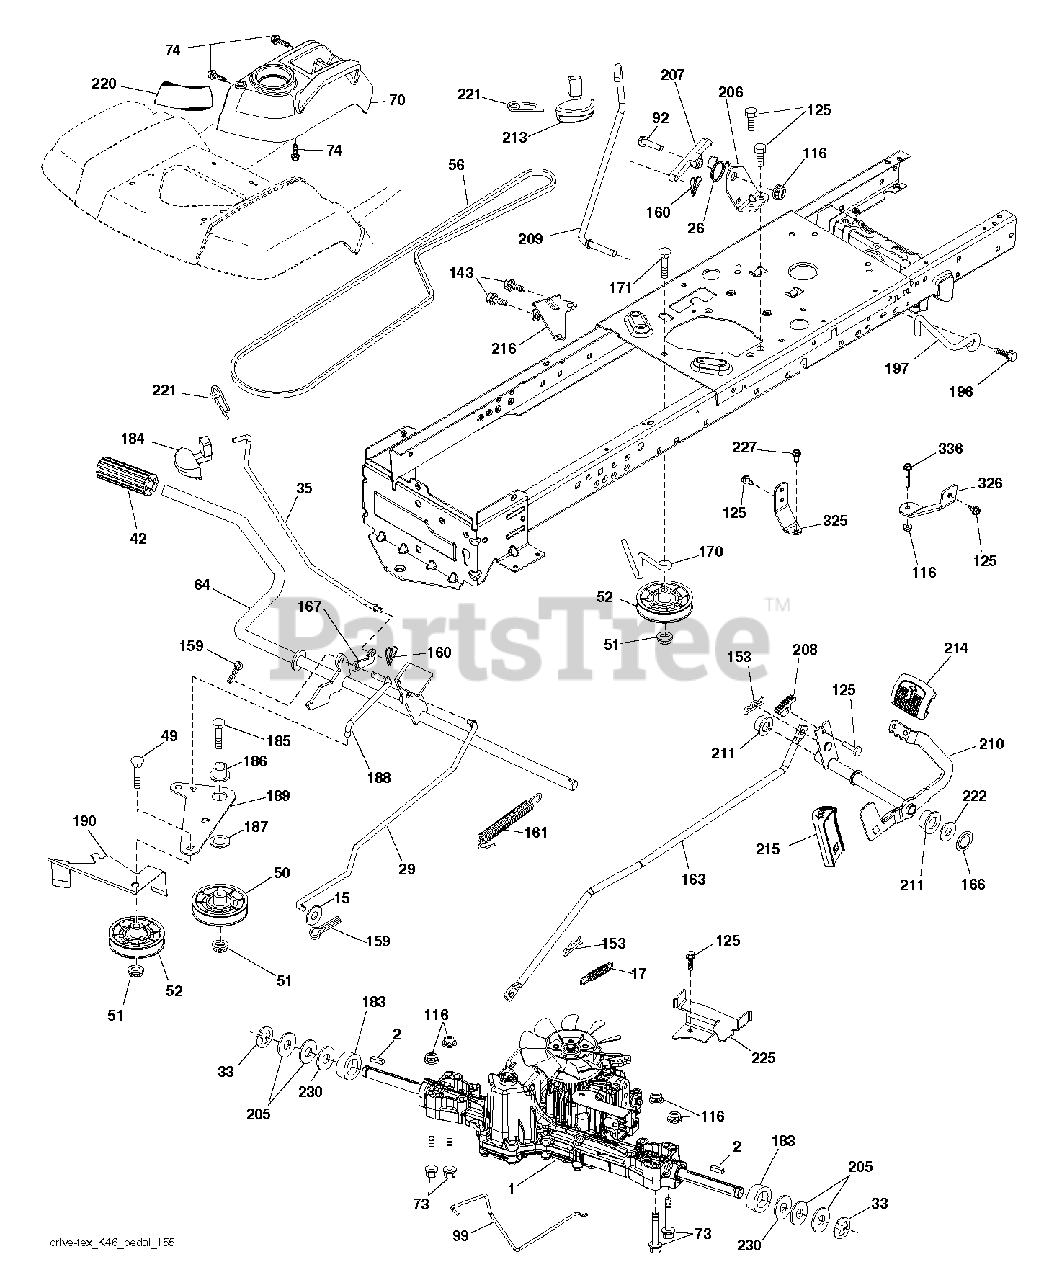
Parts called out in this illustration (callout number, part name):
2	SQUARE KEY
15	WASHER
17	SPRING.BRAKE.K46.GREEN
26	SPRING.RETURN.CRUISE
29	ROD.BRAKE.K46
33	E RING HYT
35	ROD .BRAKE. PARKING. GT. HUSQ.
42	PEDAL COVER T
50	IDLER.FLAT.910.OFFSET
51	NUT LOCK FLG 3/8-16 UNC
52	IDLER.V-GROOVE.910.OFFSET
56	V-BELT.MOWER.92.40.42/K46
64	SHAFT.ASM.PEDAL.BRK.CNTR
70	CONSOLE.ASM.RH.GT.FC.HUSQ
74	SCREW.HI-LO.CONSOLE
92	BOLT
99	ROD.SPRING.BYPASS.K46.LT.Z
116	NUT LOCK HEX FLANGE 5/16-18
125	SCREW
143	SCREW LT
153	RETAINER M
159	COTTER PIN
160	RETAINER CLIP
161	SPRING, RETURN LT
163	ROD.CONTROL.K57R.K46
166	NUT.PUSH.625
167	LATCH.BRAKE.SPRING
170	KEEPER.V-IDLER.CENTER.
183	SPACER AXLE
184	RB HANDLE.PARKG.BRK.HUS/PRED
186	SPACER.RETAINER
187	WASHER 12/32X2X10GA
188	RP LINK.CLUTCH.GROUND.DRIVE
189	BELLCRANK.GROUND.DRIVE.TEX.
190	KEEPER.BELLCRANK.DRIVE
196	SCREW 3/8-16X1
197	CLUTCH.ANTIROTATION.WIREFORM.
206	BRACKET.MOUNT.CRUISE.LATCH
207	LATCH.CONTROL.CRUISE
208	GEAR.SECTOR.CONTROL.CR
209	ROD.CONTROL.CRUISE.GT.
210	ROCKER.ASM.PEDAL.CONTR
211	BEARING.NYLON
213	KNOB.CONTROL.CRUSIE.HU
214	PEDAL.FORWARD.PAD.TEX
215	PEDAL.REVERSE.TEX.GT.4
216	BRACKET.PULLEY.IDLER.W/TEX
220	REFLECTOR.RH.TEX GT
221	RETAINER.SPRING.CLIP.H
222	WASHER 21/32 X 1-1/4 X 10 GA.
225	KEEPER.BELT.TRANSAXLE.K46
227	SCREW
230	WASHER.HARDENED
325	BRACKET.TRQ.STP.46.20".TIRE.LH
326	BRCKT.PNT.TRQ.STP.46.20TIRE.RH
336	BOLT.5/16-18X1-3/4.FLANGED.HEX
